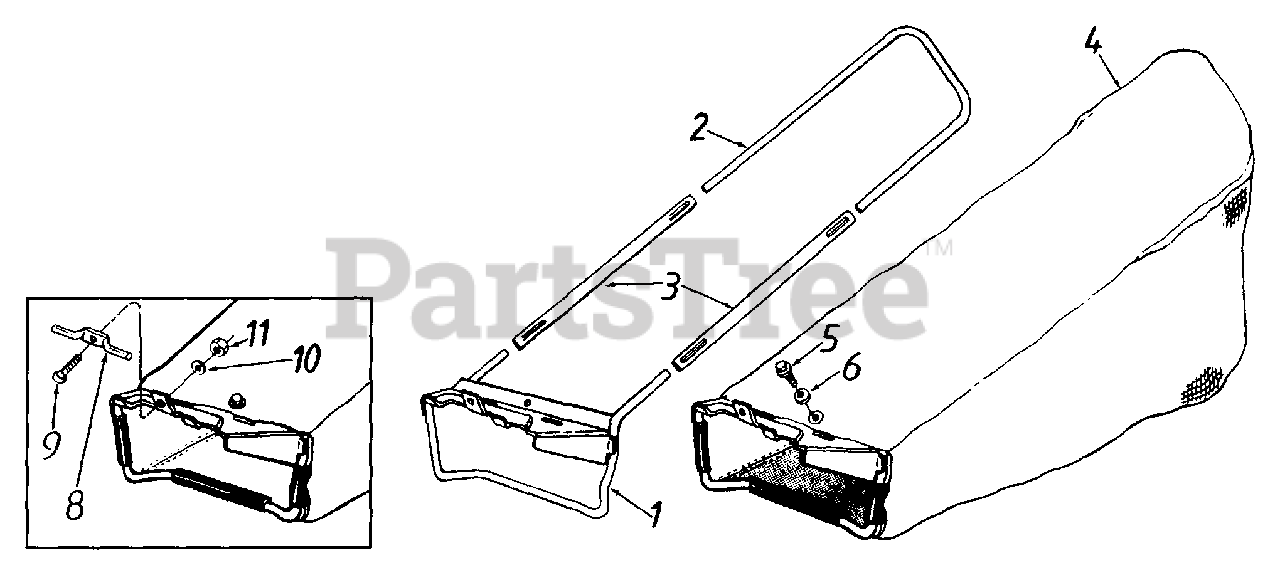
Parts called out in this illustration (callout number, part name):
1	Frame - Lower Ass'y.
2	Frame - Upper
3	Tube Support
4	Grass Bag
5	Hex Wash. Hd. TT-Tap Scr. 1/4-20 x 5" Lg.
6	Bell-Wash. 1/4" I.D.
8	Grass Bag Hook
9	Hex Bolt 1/4-20 x .62" Lg.
10	L-Wash. 1/4" I.D.
11	Hex Nut 1/4-20 Thd.
